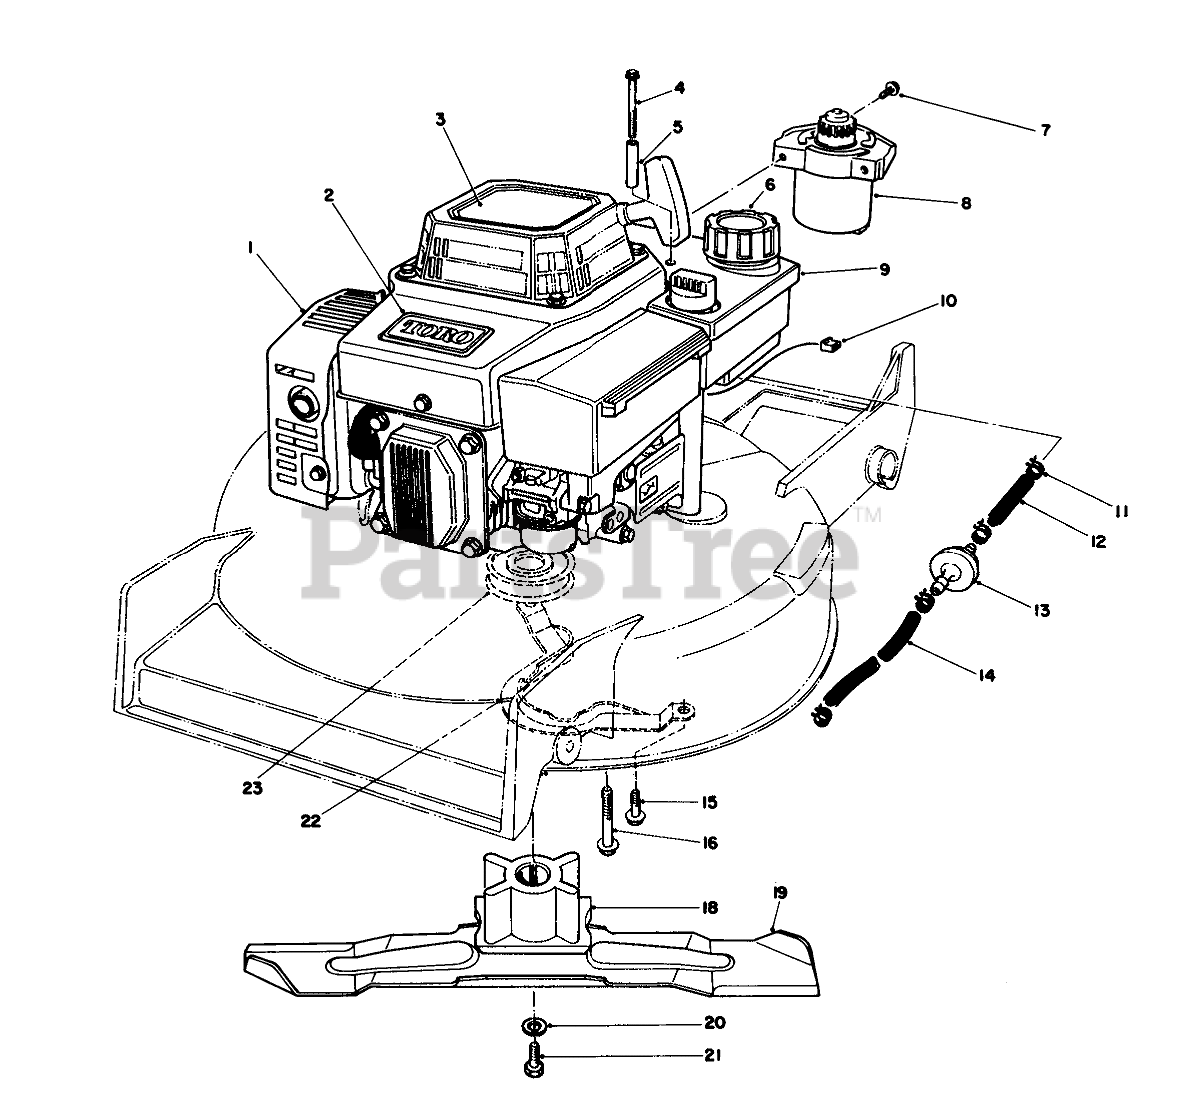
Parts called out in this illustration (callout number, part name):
2	TORO LOGO PLT
3	DECAL-HV INT'L
4	THRD FORMING SCREW
5	TUBULAR SPACER
6	GAS CAP ASM
7	SCREW
8	STARTER MOTOR ASM
9	TANK ASM
10	CONNECTOR BODY
11	CLAMP-FUEL LINE
12	LINE-GAS
13	FILTER-FUEL
14	HOSE-FUEL
15	Screw
16	SCREW-HWHTF
18	BLADE RETAINER
19	BLADE-21in
20	WASHER-LOCK
21	SCREW-BLADE
22	BELT GUIDE
23	PULLEY-DRIVE, ZONE START
